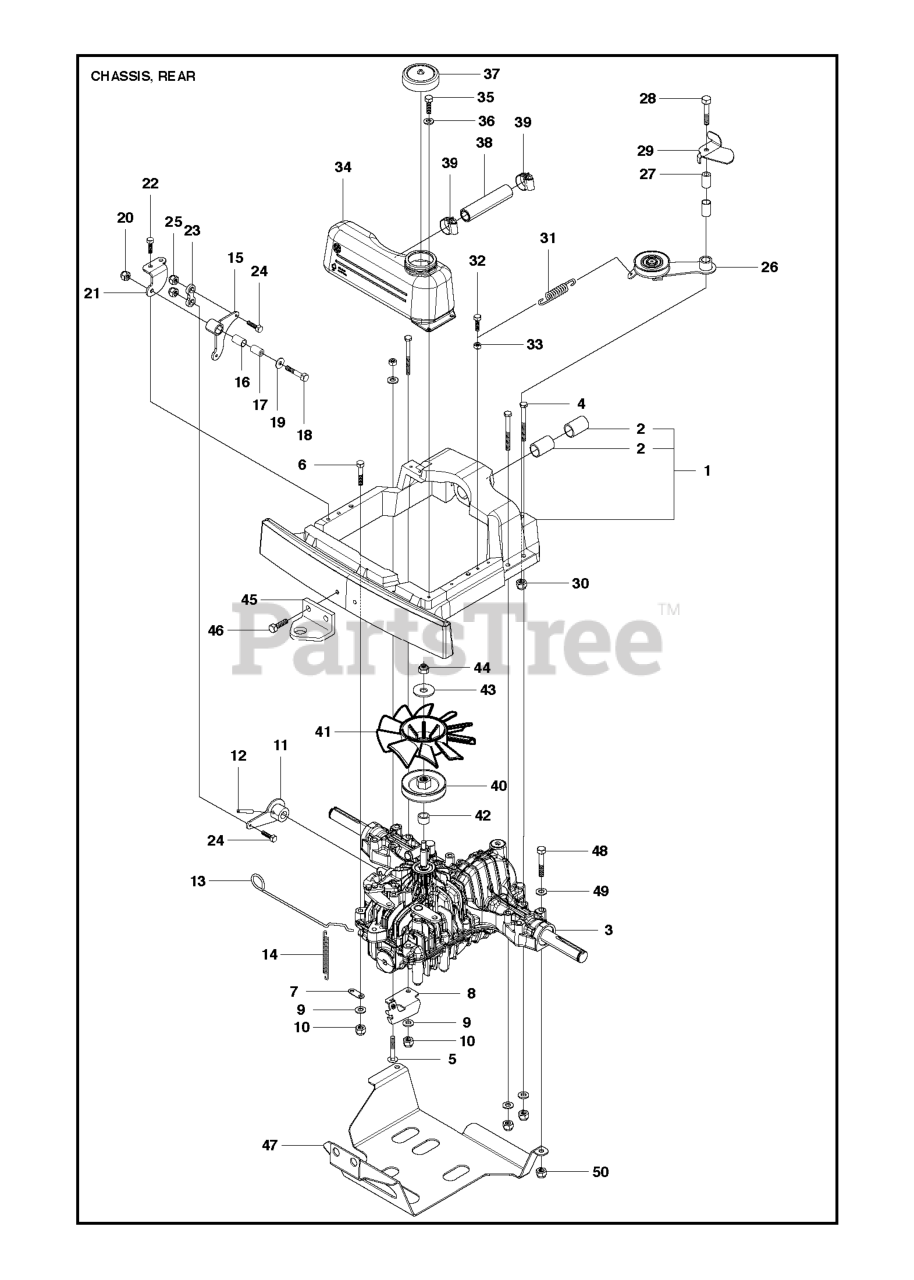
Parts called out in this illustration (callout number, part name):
9	WASHER BRB 8.4X17
10	LOCKNUT M8
18	SCREW
20	LOCKNUT M8
22	REPL BY 725 24 49-51
24	SCREW M6S 5X20
25	LOCKNUT M5
30	LOCKNUT M8
34	EXPANSION TANK K664
35	BOLT FLANGE - M6X20
36	WASHER - 26X6.5X1.6
44	NUT
46	Screw M10x25
49	WASHER BRB 8.4X17
50	LOCKNUT M8
